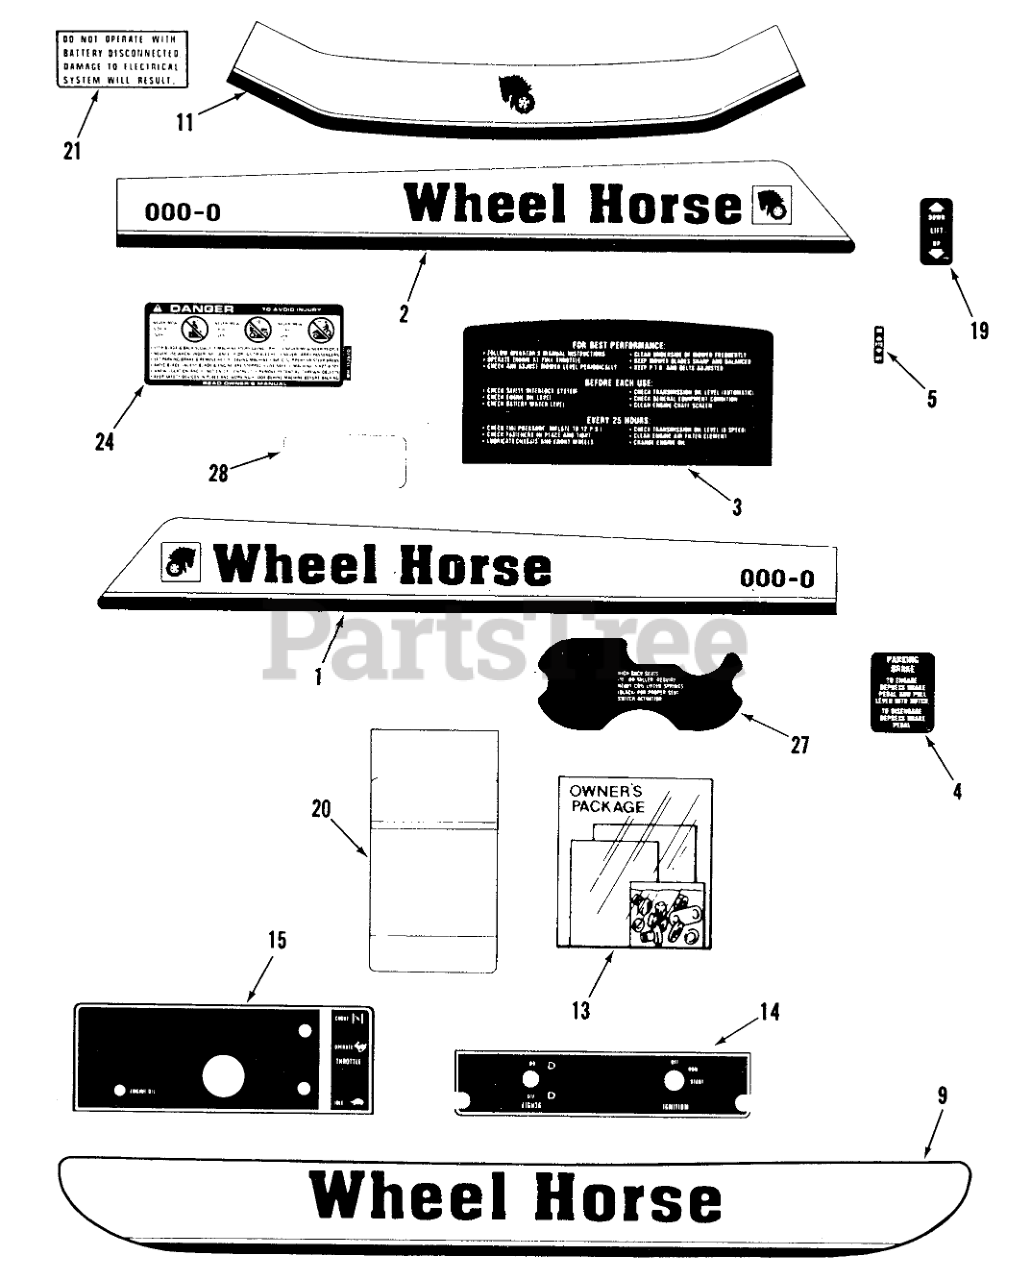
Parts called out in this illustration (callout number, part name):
3	DECAL-REAR HOOD
4	DECAL-PARKING-BRAKE
5	DECAL PTO CLUTCH
9	DECAL-FENDER
11	DECAL-FRONT HOOD
13	New Tractor Loose Parts Package 220-4
14	DECAL BACK PLATE
15	Decal-Dash 252-H
19	DECAL-LIFT
20	Decal-Maintenance
21	DECAL ELECT SYSTEM
24	DECAL-DANGER
27	DECAL-SEAT LIFTER
28	DECAL-OVERLAY
